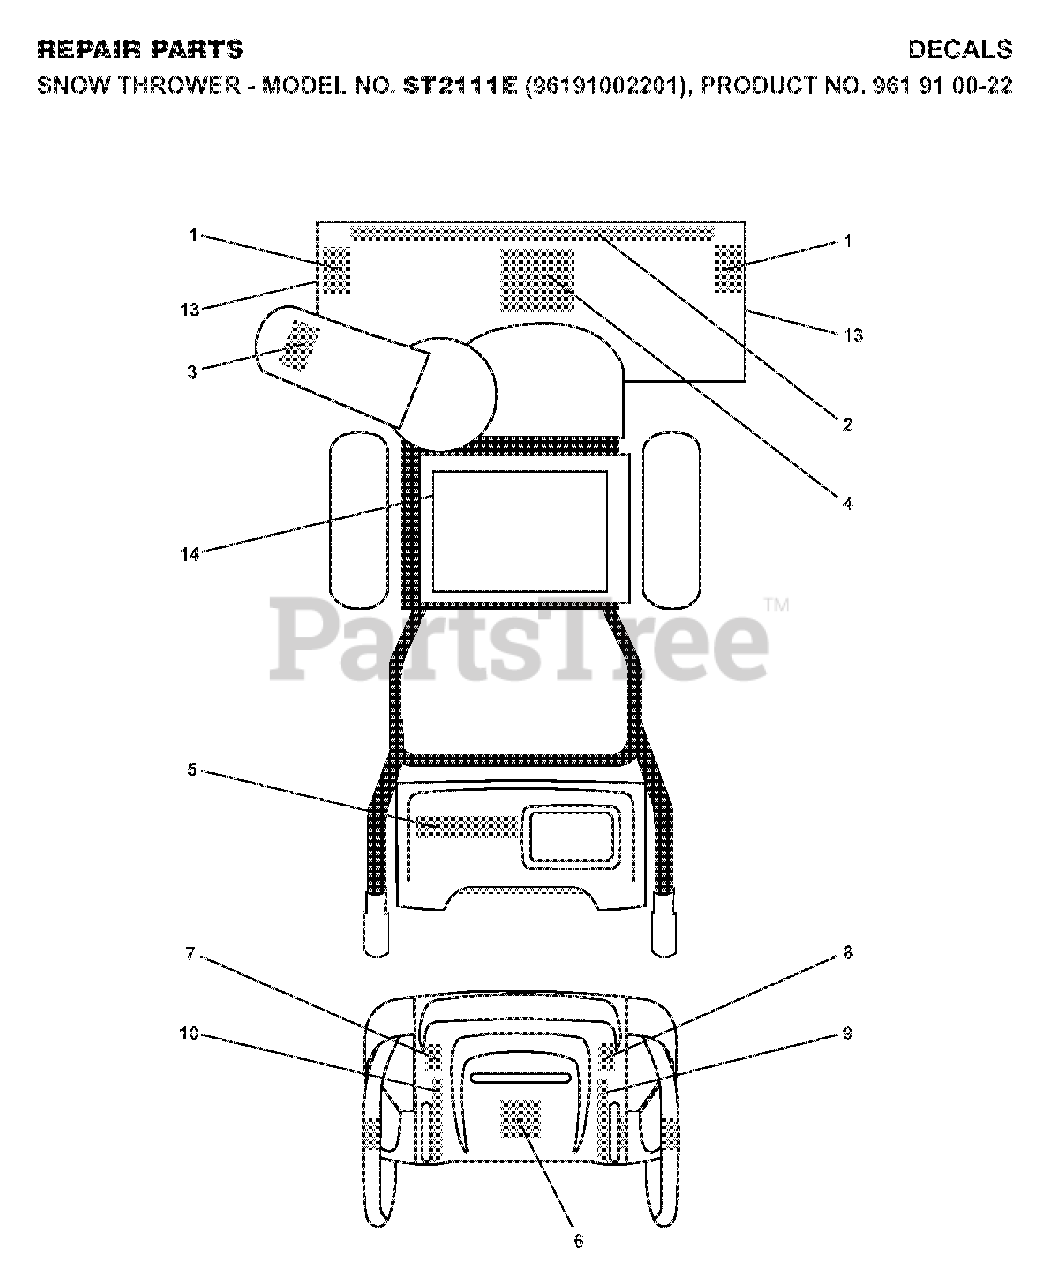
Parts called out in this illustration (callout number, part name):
1	DECAL.AUGER.SAFETY.
3	DECAL.CHUTE.SAFETY.
4	DECAL.AUGER."
6	DECAL.CONSOLE.INSTRUCTION
7	DECAL.POWER.STEER.LT.TRIG.INT
8	DECAL.POWER.STEER.RT.TRIG.INT
10	DECAL.REM.DEFLECTOR.LT
14	DECAL.BELT.GUARD.
